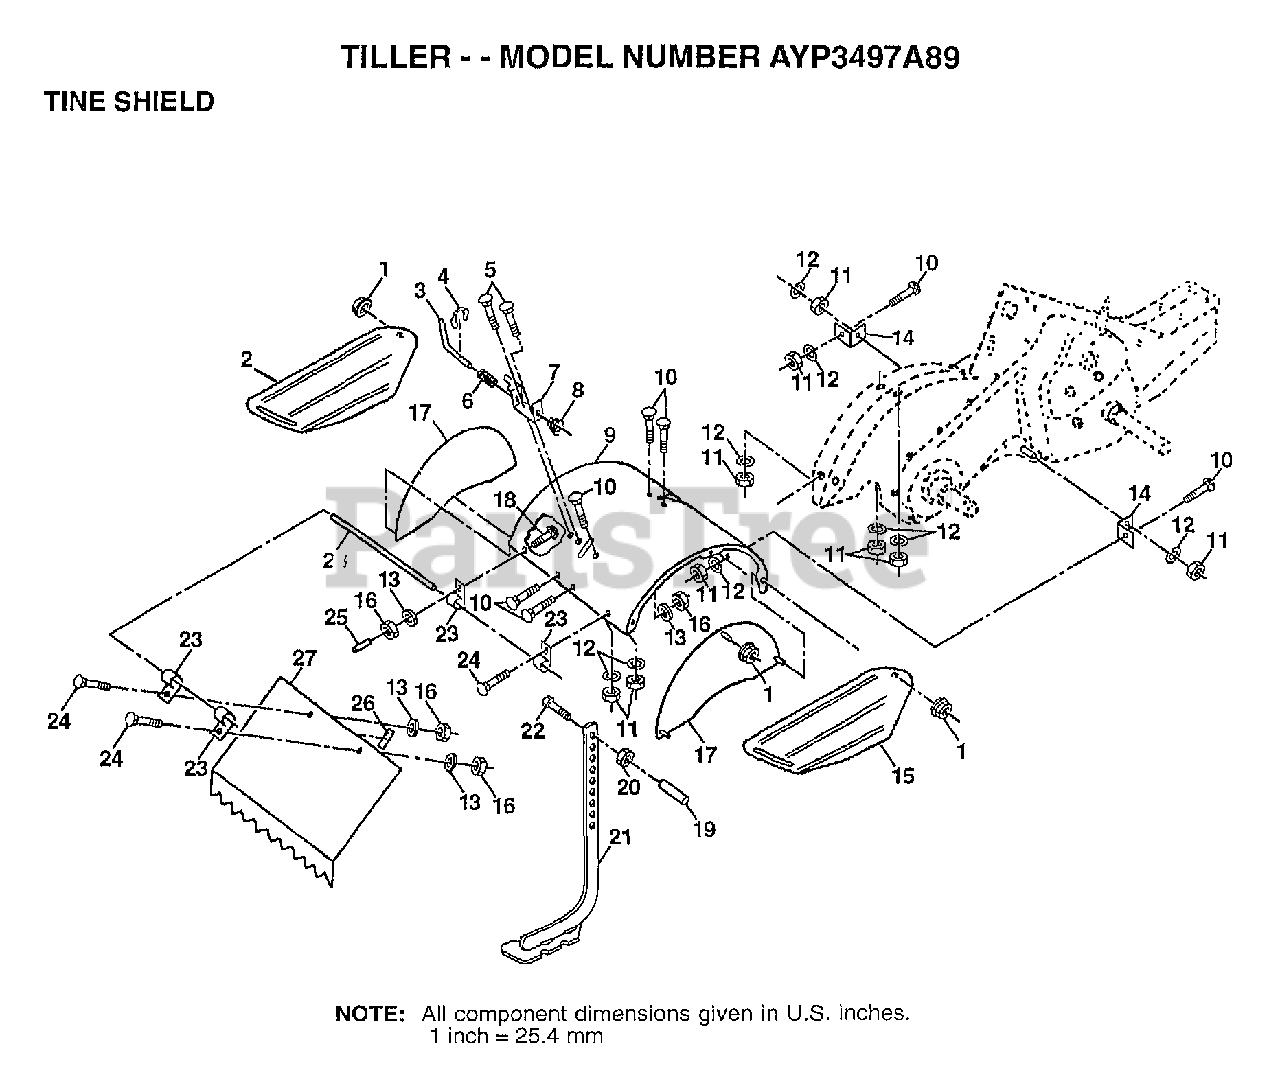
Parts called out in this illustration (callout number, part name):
1	NUT
2	SHIELD.SIDE.O/LH
3	STAKE PIN TI
4	KLIP RING TI
5	BOLT
6	SPRING TI
7	LATCH BRACKET TI
8	SPRING CRT
9	SHIELD TINE RED
10	BOLT
11	NUT.HEX.5/16-18
12	LOCKWASHER
13	LOCKWASHER
14	TINE SHLD BRKT TI
15	SHIELD.SIDE.O/RH
17	SHIELD SIDE RED
18	BOLT
19	GRIP CRT
20	NUT.HEX.3/8-16UNC
21	STAKE.ASM.DEPTH
22	BOLT
23	HINGE CRT
24	BOLT.1/4-20X1/2
25	VINYL CAP TI
26	PAD IDLER TI
27	SHIELD LEVELING
28	PIN.HINGE
